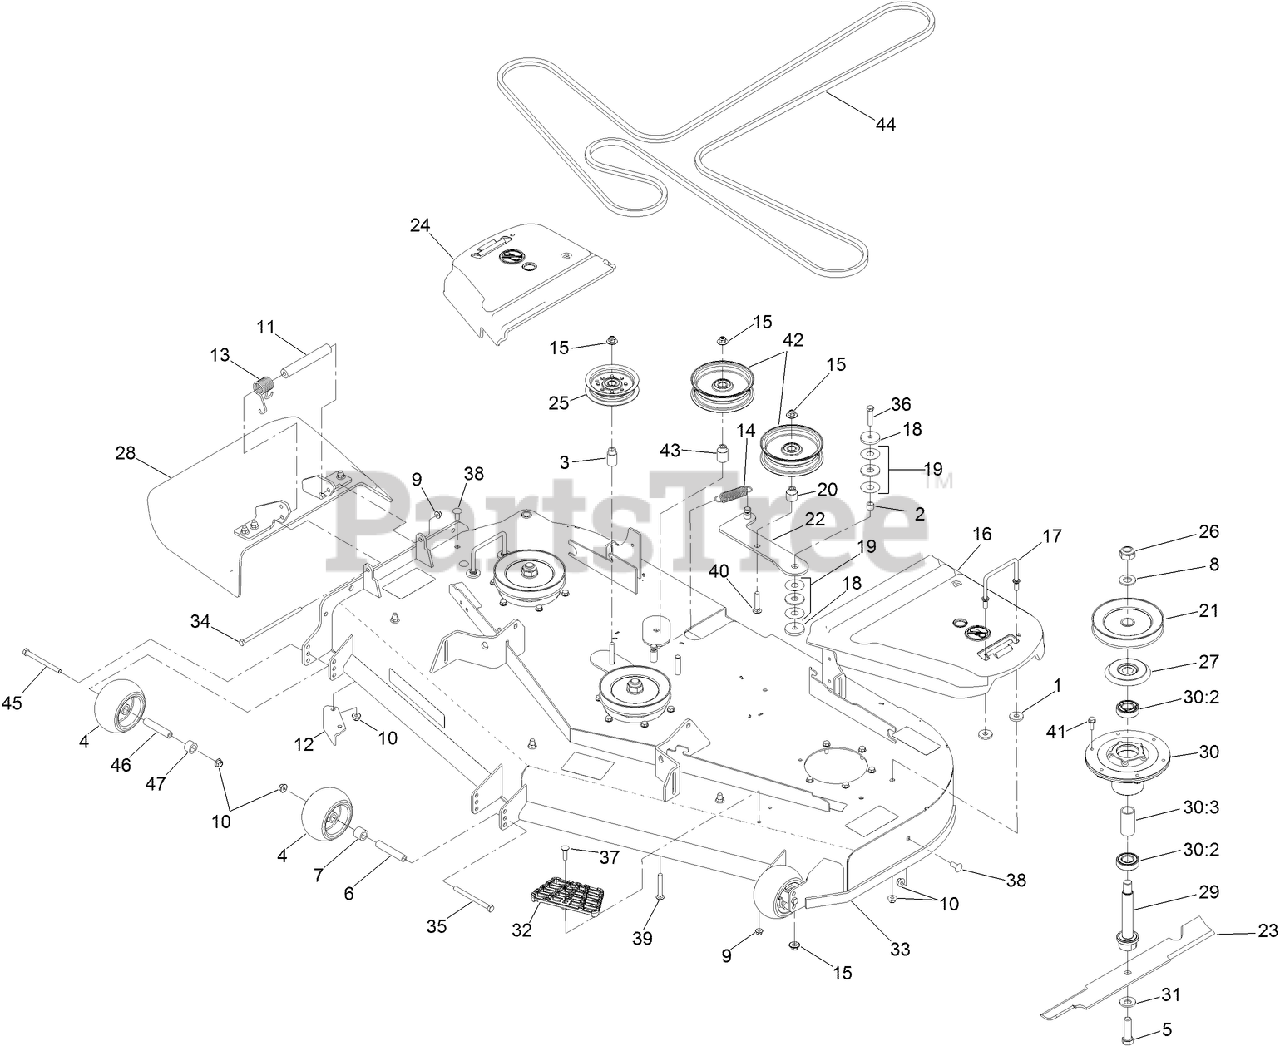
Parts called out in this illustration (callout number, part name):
1	WASHER
2	BUSHING-LEVER, LIFT
3	BUSHING-IDLER
4	ROLLER-SCALP, ANTI
5	SCREW-BLADE
6	TUBE-SPANNER
7	TUBE-SPACER
8	WASHER
9	NUT-HF, NI
10	NUT-HF, NI
11	SPACER
12	BAFFLE-DISCHARGE
13	SPRING-TORSION
14	SPRING-EXTENSION
15	NUT-FLANGE, NI
16	COVER-BELT, LH
17	WIREFORM-COVER
18	WASHER-PLAIN
19	WASHER-FRICTION, COMPOSITE
20	BUSHING-IDLER
21	SHEAVE-DRIVE, BLADE
22	ARM-IDLER
23	BLADE-ROTARY, 20.5IN (HI FLOW)
24	COVER-BELT, RH
26	NUT-LOCK, NI
27	SHIELD-BEARING
28	DEFLECTOR ASM
29	SHAFT-SPINDLE
30	SPINDLE ASM
30:2	BEARING-BALL
30:3	SPACER-BEARING
31	WASHER-BELLEVILLE
32	STEP-DECK
33	DECK DECAL ASM
34	SCREW-HH
35	SCREW-HH
36	SCREW-HH
37	SCREW-CARR
38	SCREW-CARR
39	SCREW-CARR
40	SCREW-CARR
41	SCREW-TAPTITE
42	IDLER-PULLEY, FLAT
43	BUSHING-IDLER
44	BELT-DECK DRIVE
45	SCREW-HH
46	TUBE-SHAFTING
47	TUBE-SPACER
